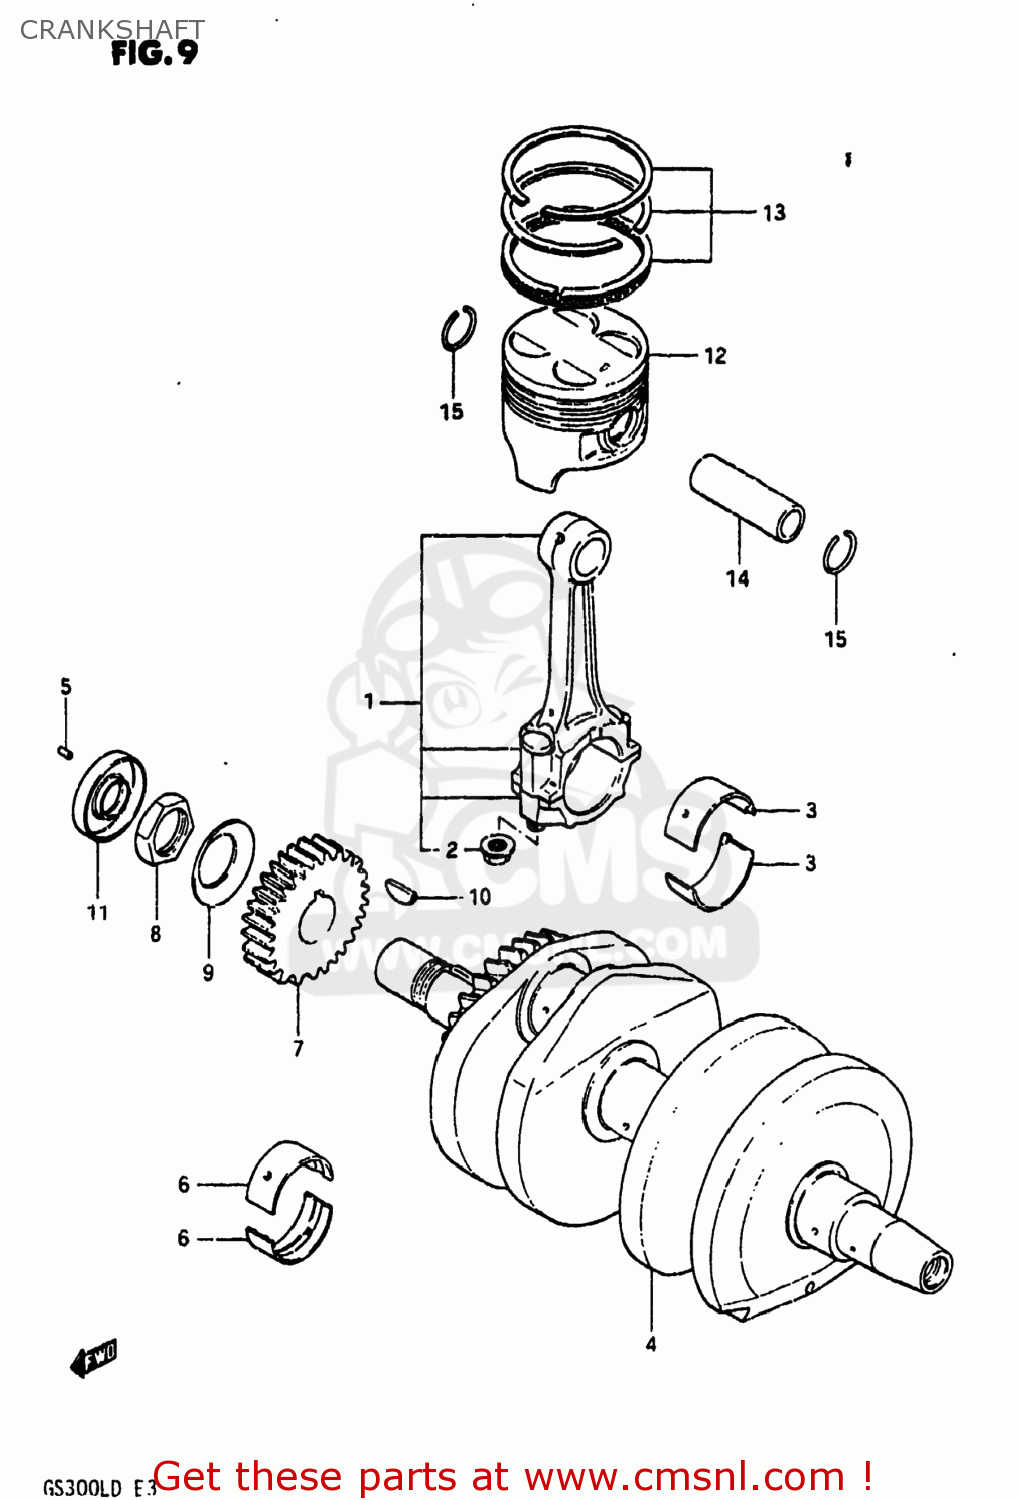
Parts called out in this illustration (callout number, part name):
1	ROD ASSEMBLY,CONNECTING
2	NUT
3	BEARING,CRANK PIN
4	CRANKSHAFT
5	PIN 3X5
6	BEARING,CRANKSHAFT(US:0.25)
7	GEAR,PRIMARY DRIVE
8	NUT
9	WASHER
10	KEY
11	OIL SEAL
12	PISTON (OS:0.5)
13	RING SET,PISTON (OS:0.5)
14	PIN,PISTON
15	CIRCLIP
